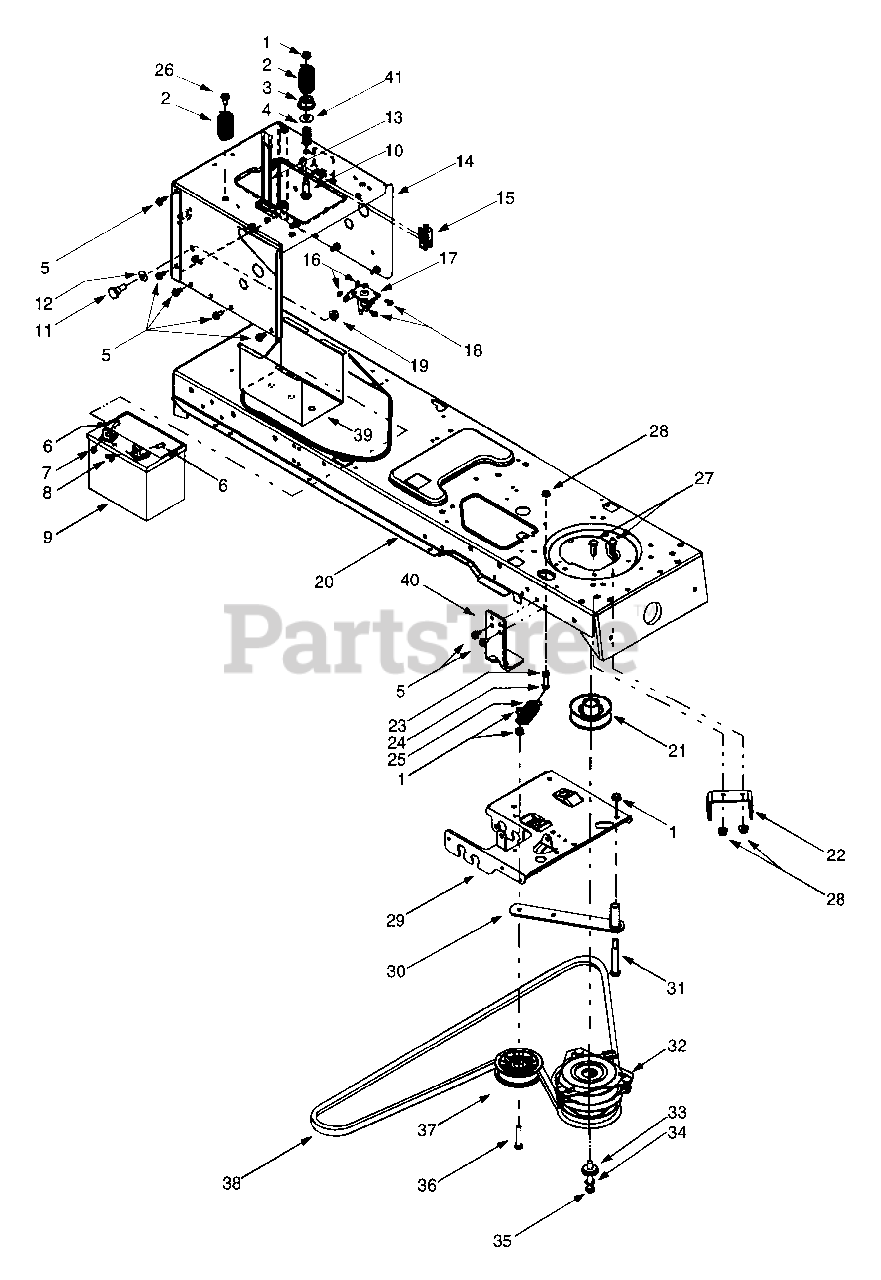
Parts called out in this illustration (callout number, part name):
1	Flange Lock Nut, 3/8-16
2	Compression Spring, 1.318 x 2.37
3	Spacer Cup, 1.5 OD
4	Compression Spring, .66 OD x 1.5
5	Self Tapping Screw, 5/16-18 x .625
6	Hex Cap Screw, 1/4-20 x .62
7	Hex Sems Nut, 1/4-20
8	Wing Nut, 1/4-20
9	12-volt Battery, 270 CCA
10	Shoulder Screw, .5 x 1.25, 3/8-16
11	Shoulder Screw, .625 x .5, 7/16-20
12	Bell Washer, .45 x 1.0 x .062
13	Battery Strap
16	Lock Washer, 1/4
17	Solenoid, 12-Volt, 100 Amp
18	Self Tapping Screw, 1/4-20 x.5
19	Flange Lock Nut, 7/16-20
24	Hex Cap Screw, 5/16-18 x 1.75 (Grade 5)
25	Extension Spring, 1.2 OD x 3.638
26	Self-tapping Screw, 5/16-18 x .875
27	Hex Cap Screw, 5/16-18 x .625
28	Flange Lock Nut, 5/16-18
29	Steering Support Bracket
32	Electric PTO Clutch
33	Shoulder Spacer, 1.38 x .445 x .36
34	Lock Washer, 7/16
35	Hex Cap Screw, 7/16-20 x 3.25 (Grade 5)
36	Hex Cap Screw, 3/8-16 x 2.25 (Grade 5)
37	Flat Idler Pulley, 3.5 OD
38	PTO Belt
41	Bell Washer, .401 x .87 x .063
